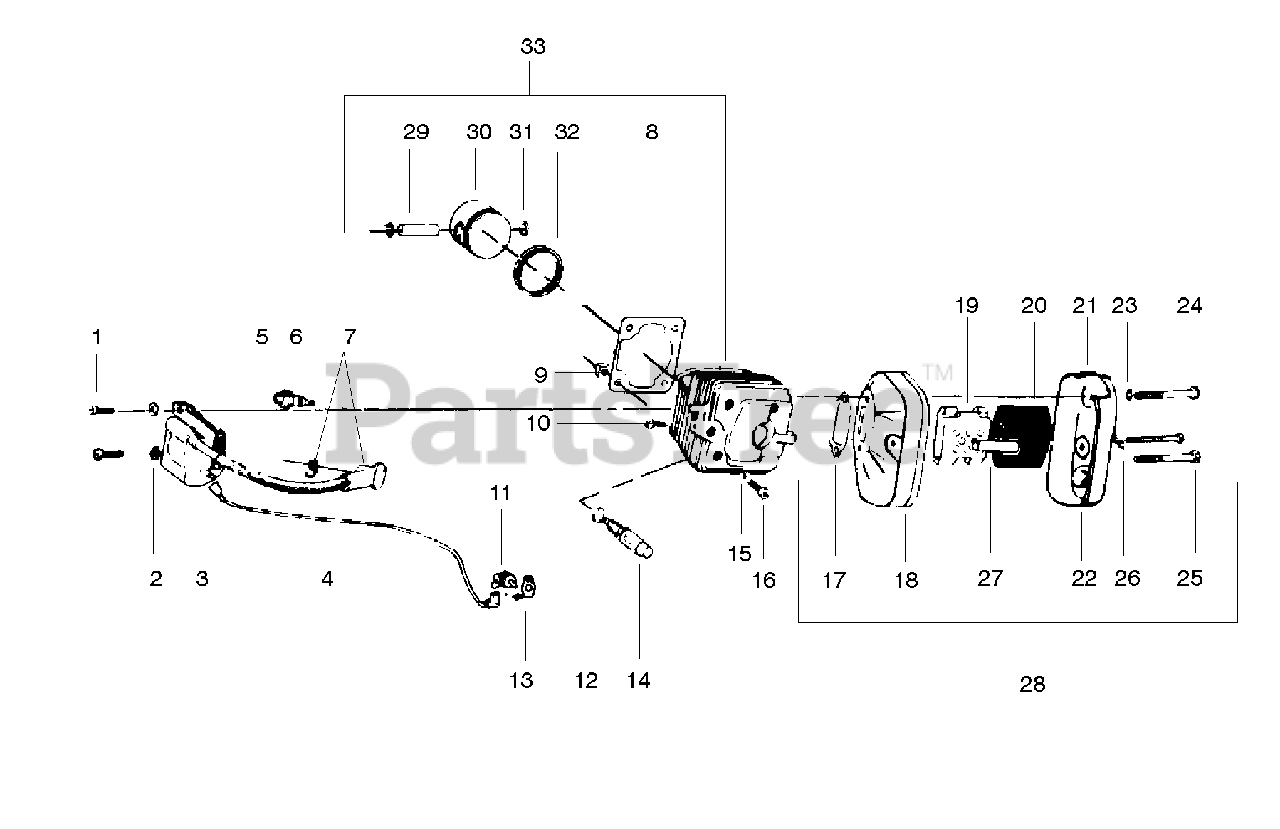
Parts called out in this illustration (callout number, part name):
3	Module & Switch Wire Ass'y.
4	Switch Wire
6	Spark Plug
7	Spark Plug Boot & Clip
8	Cylinder Base Gasket
11	Grounding Switch
13	Switch Plate
14	Decompression Valve
17	Muffler Gasket
18	Muffler Body
19	Muffler Channel
20	Muffler Screen
21	Muffler Cover Ass'y.
22	Heat Shield Ass'y.
23	Lockwasher
26	Lockwasher
28	Muffler Ass'y.
29	Wrist Pin
30	Piston & Rings
31	Retainer
32	Piston Ring Set
33	Cylinder & Piston Kit
